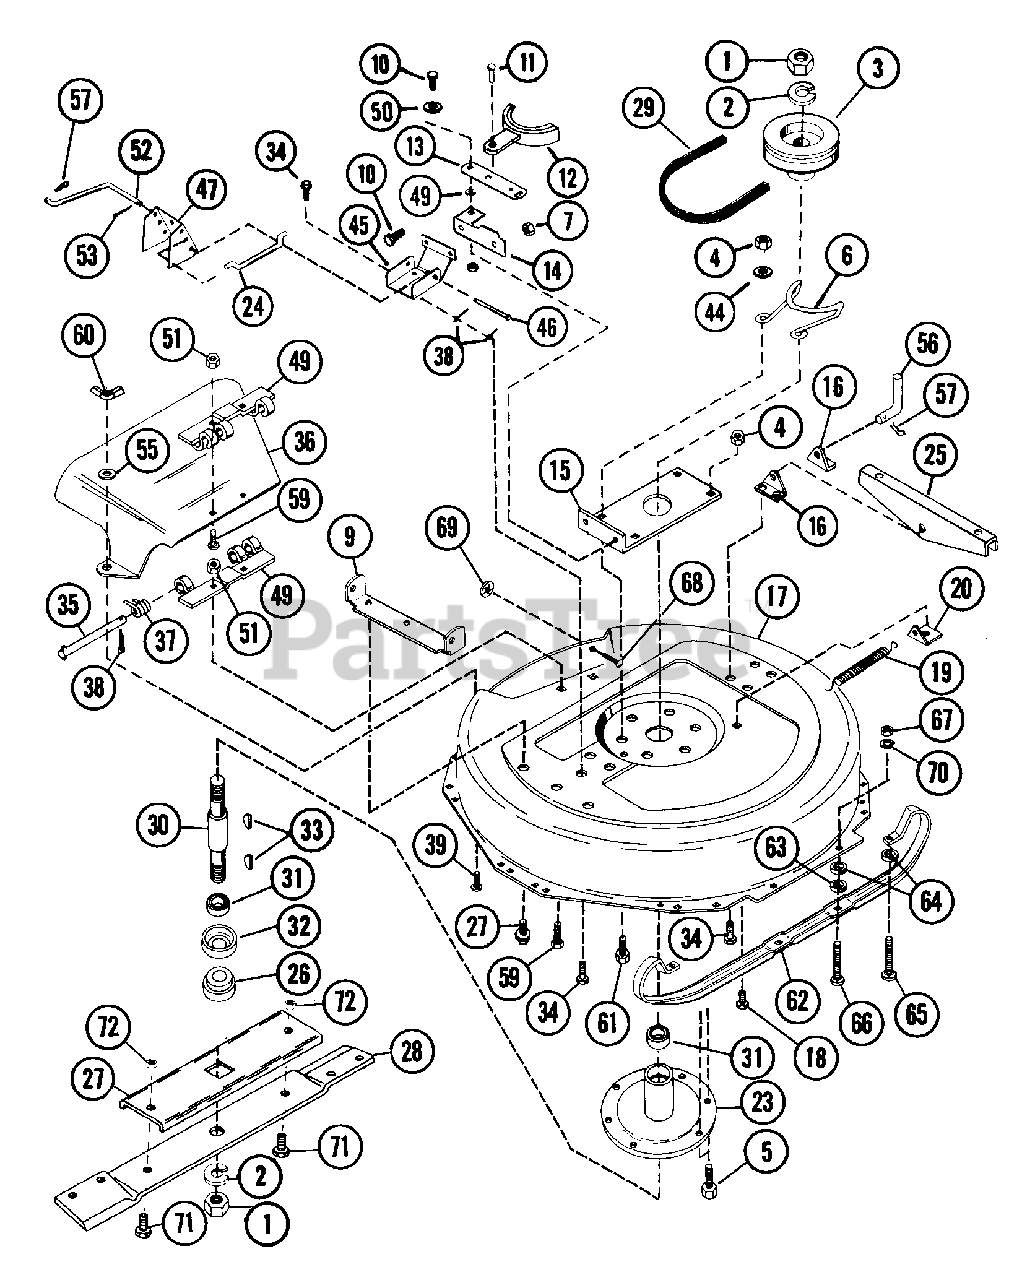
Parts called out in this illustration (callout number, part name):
1	NUT-JAM .75-10 PL
2	WSHR-LK .750X.188 MED PL
3	MOWER SHEAVE
4	NUT-LK-CTR .375-16 GR A PL
6	MOWER BELT FINGER
7	NUT-LK .312-18 GR A PL
8	MOWER ENGAGING ARM
9	FRONT MOUNTING BRACKET
10	BLT-HEX .31-18X.63 PL GR 2
11	RVT .25X.50 RH ST
12	BLADE BRAKE
13	MOWER BRAKE LEVER
14	BRAKE BRACKET
16	REAR MOUNTING BRACKET
17	28 IN MOWER PAN SERVICE ASSEMB
18	BLT-SERHFWH .25-20X.50 PL
19	SG-TENS .072X.51X5.31 WLD 25
20	BRAKE CLIP
21	BLT-SCRHFWH .38-16X.50 PL
23	SPINDLE HOUSING
26	RETAINER HUB
27	BLADE TRAY
28	MOWER BLADE 28
29	V-BELT
30	SPINDLE SHAFT
31	BRG-BALL .750X1.781X.61
32	BEARING SLINGER
33	KEY-WDRF .188X.75X.313 SAE 9
34	BLT-SERHFWH .31-18X.50 PL
35	CLEVIS PIN
36	DISCHARGE CHUTE
37	SG-TORS .090X.37X.63
38	PIN-COTR .09X.75 PL
39	BLT-RDHDSQNK .25-20X.75 GR5PL
44	WSHR-FL-STL .406X.865X.094 PL
45	PIVOT BRACKET
46	PIN-CLEV .309X3.50 SP
47	SWIVEL BRACKET
49	HINGE PLATE
51	NUT-LK-CTR .250-20 PL
52	MOWER ENGAGEMENT LINK
53	PIN-COTR .12X.75 PL
54	SPACER
55	WSHR-FL-STL .328X1.0X.094
56	CLEVIS PIN
57	PIN-HAIR INT .08X.38X1.42 YWZC
58	MOWER BRAKE LINK
59	BLT-RDHDSQNK .25-20X.62 PL
60	NUT-WING .250-20
61	BLT-HEX .38-16X1.00 PL
62	28 IN ADJUSTABLE SKID
63	SPACER BUSHING .5 X .32 X .21
64	SPACER .328X.750X.375
65	BLT-RDHDSQNK .31-18X1.25 SHTPL
66	BLT-RDHDSQNK .31-18X1.75 SHTPL
67	NUT-HEX .312-18
68	BLT-RDHDSQNK .312-18X.62SHTPL
69	NUT-PUSH .312
70	WSHR-LK .312X.097 PL HVY
71	BLT-HEX .38-16X1.00 PL GR5
72	NUT-LK TOP .375-16 GR C YWZC
